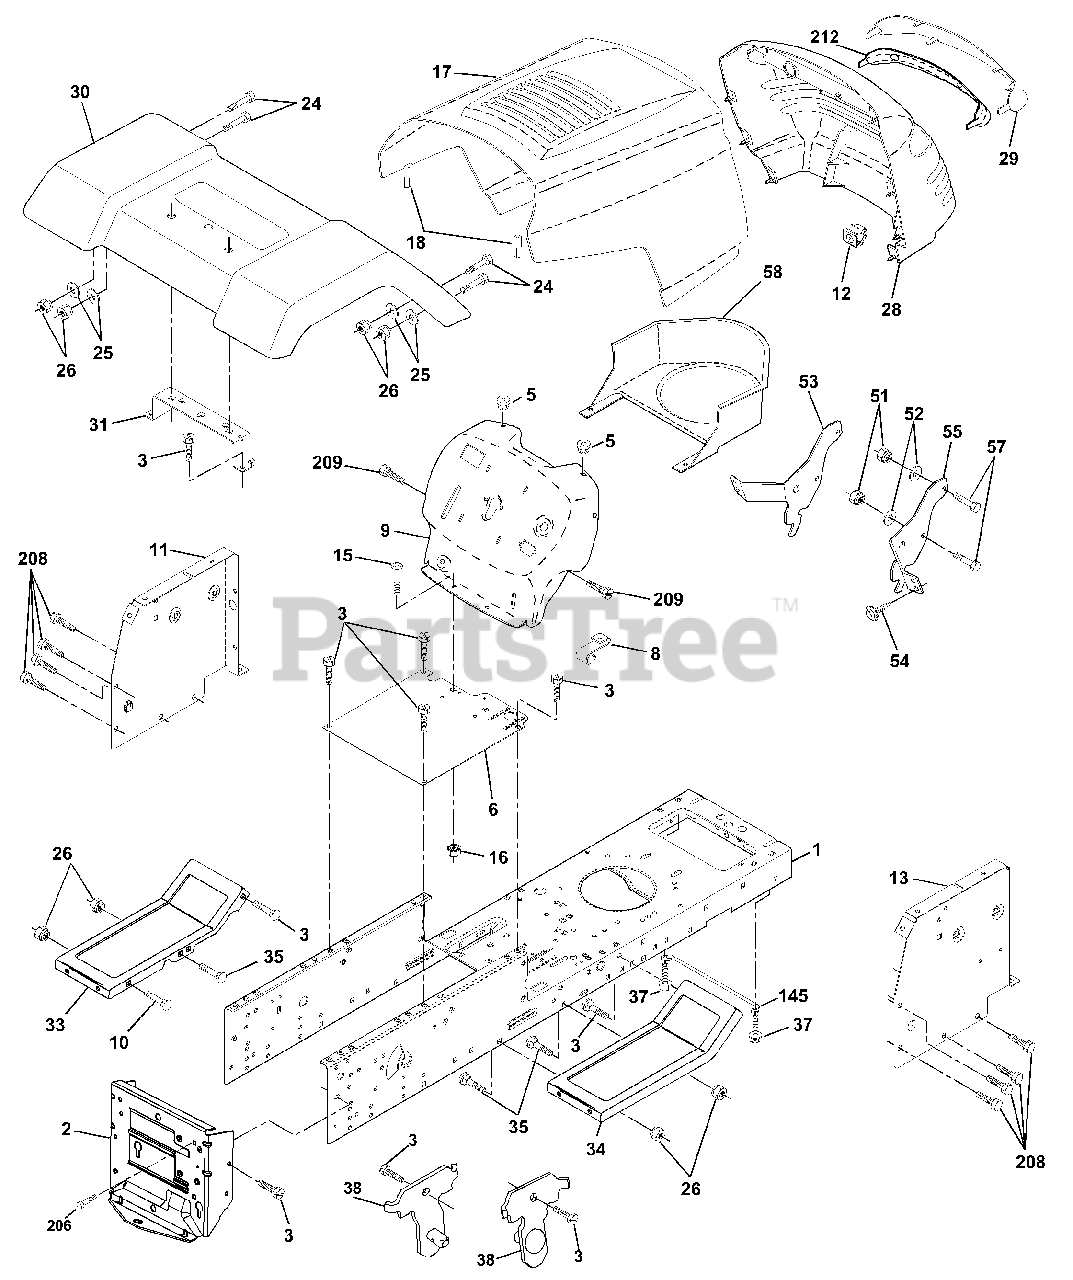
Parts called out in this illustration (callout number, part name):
2	Drawbar, Stretch
3	Screw 3/8-16 x 3/4
5	Bumper, Hood/Dash
6	Saddle Silkscreen Flt Sdl
8	Clip Retainer Slide-On
9	Dash
10	Bolt, Carriage 3/8-16 x 1
11	Panel Dash LH
12	Clip Tinnerman Grille P.L
13	Panel Slkscr Dash RH
14	Screw Thdrol 3/8-16 x 1/2 Ty-tt
15	Screw Mach TRHD 5/16-18 unc x 3/4
16	Nut Keps 5/16-18 Unc
17	Hood
18	Bumper Hood
24	Bolt Fin Hex 3/8-16 unc X 1 Gr. 5
25	Washer 13/32 X 13/16 X 12 Ga
26	Nut Lock Hex w/Ins 3/8-16 Unc
28	Grille/Lens Asm
29	Lens Grille Private Label
30	Fender
31	Bracket Fender Repl 109873x
33	Footrest Pnt LH Perf
34	Footrest Pnt RH Perf
35	Bolt Rdhd Sht Sqnk 3/8-16 X3/4
37	Screw Thdrol 5/16-18 x 1/2 TYT
38	Bracket Asm. Pivot Mower Rear
51	Nut Lock W/Insert 1/4-20unc
52	Washer 9/32 x 7/8 x 16 Ga.
53	Bracket Grille Lh
54	Screw Hex 8-18 x 7/8
55	Bracket Grille Rh
57	Bolt Fin Hex 1/4-20 unc x .75
58	Duct Air Engine PL/LT
145	Rod Pivot Chassis/Hood
206	Bolt Shoulder 5/16-18
208	Screw Thdrol 3/8-16 x 1/2
209	Screw Hex Wsh Thdrol 3/8-16
212	Insert Lens Reflect
